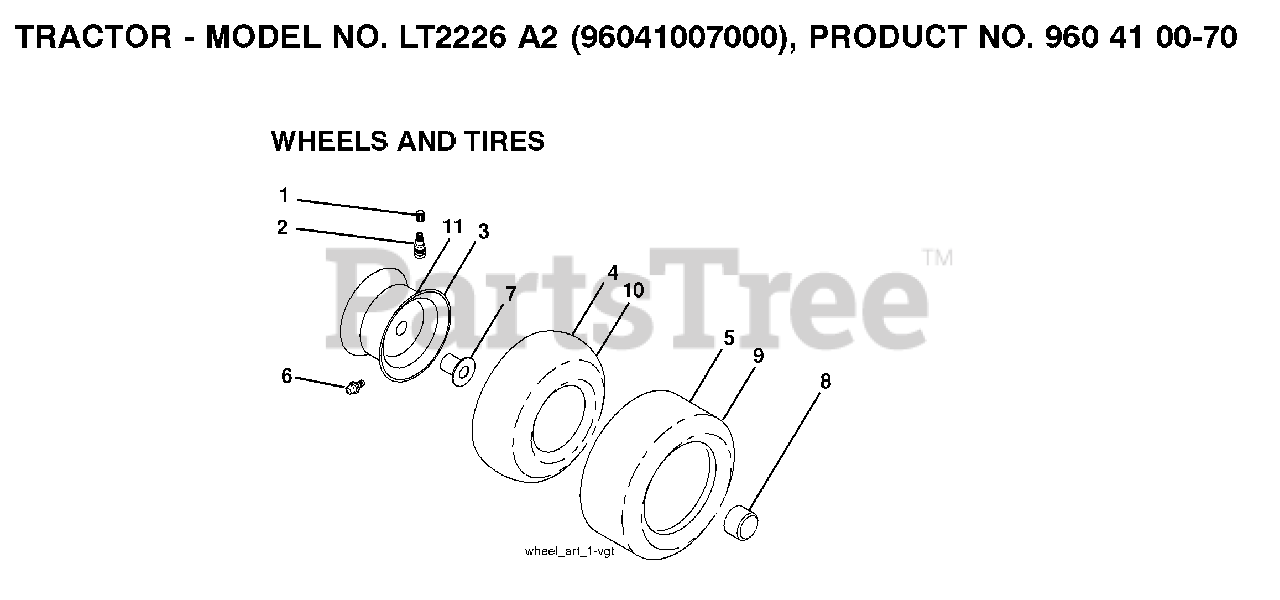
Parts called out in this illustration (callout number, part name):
1	VALVE CAP
2	VALVE STEM LT
3	RIM ASM 6" FRONT SILVER
4	TUBE.5.3/4.5/6
5	TIRE HEAVY DUTY
6	FITTING LT
7	BEARING T
8	CAP, AXLE BLK
9	TIRE.TS.20X10-8
10	TUBE
11	RIM ASM 8" REAR SILVER
